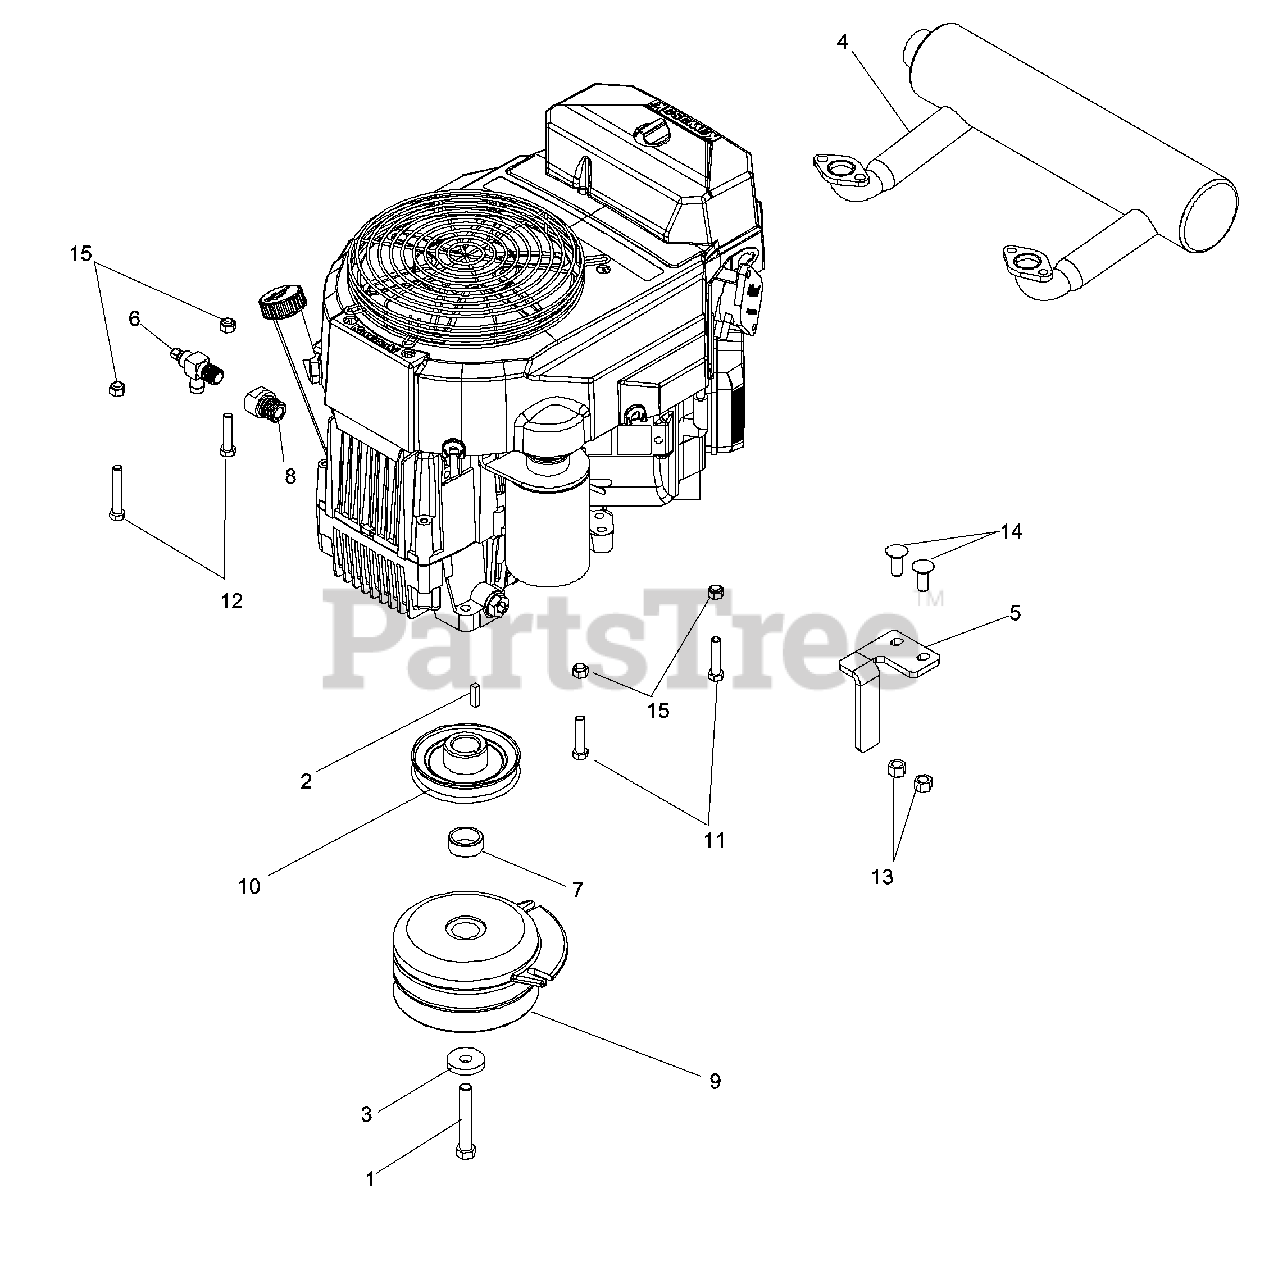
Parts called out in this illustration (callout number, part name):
1	HCS 7/16-20 X 2-3/4
2	KEY - 1/4 X .88
3	WASHER .43X1.38X.25
4	MUFFLER
5	ANCHOR CLUTCH
6	OIL DRAIN
7	HUB BEARING SPACER
8	ADAPTER, OIL DRAIN
10	DRIVE PULLEY-ENGINE
11	CAPSCREW 5/16 X 1/1/2 HEX HEAD
12	HCS 5/16-18X2
13	NUT 3/8-16 NYLOC
14	RHSNB 3/8C X 1
15	NUT 5/16 NYLOC
